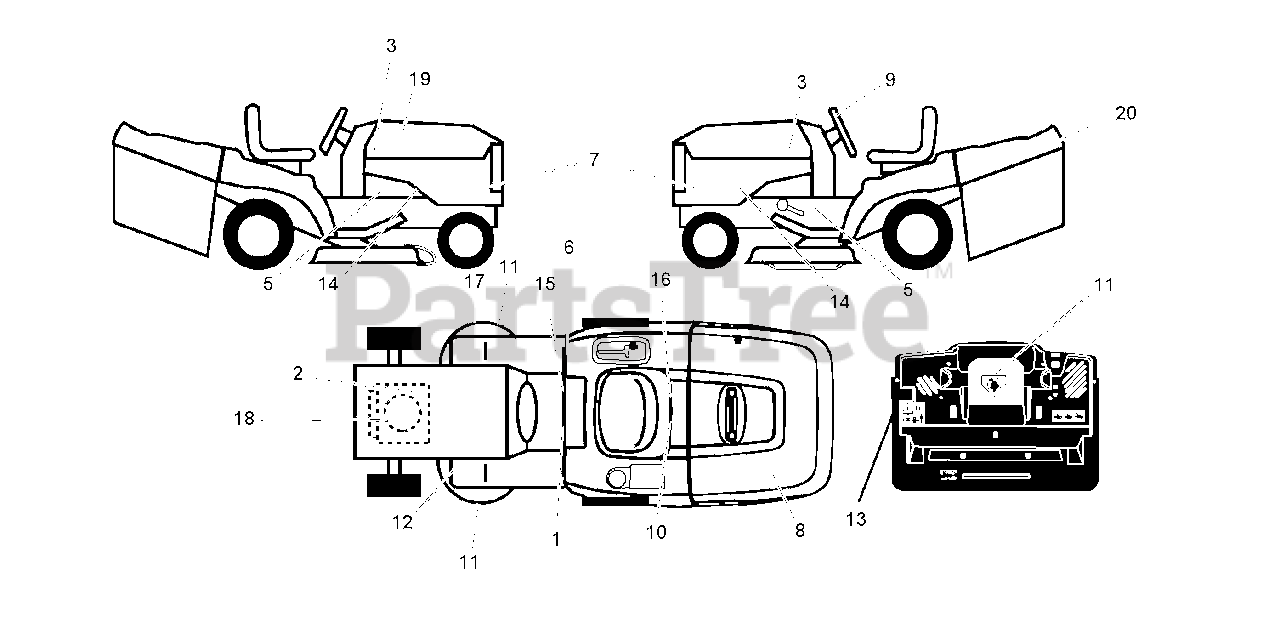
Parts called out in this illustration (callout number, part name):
1	LABEL
2	DECAL
6	Decal, Fender 100 DB/CE
10	DECAL BTRY SYMBOLS
11	DECAL.INTERNATIONL.CUTFINGER
12	DECAL
13	DECAL
15	DECAL PARK BRAKE
16	DECAL.BYPASS.FENDER.CRD.LT.YT
